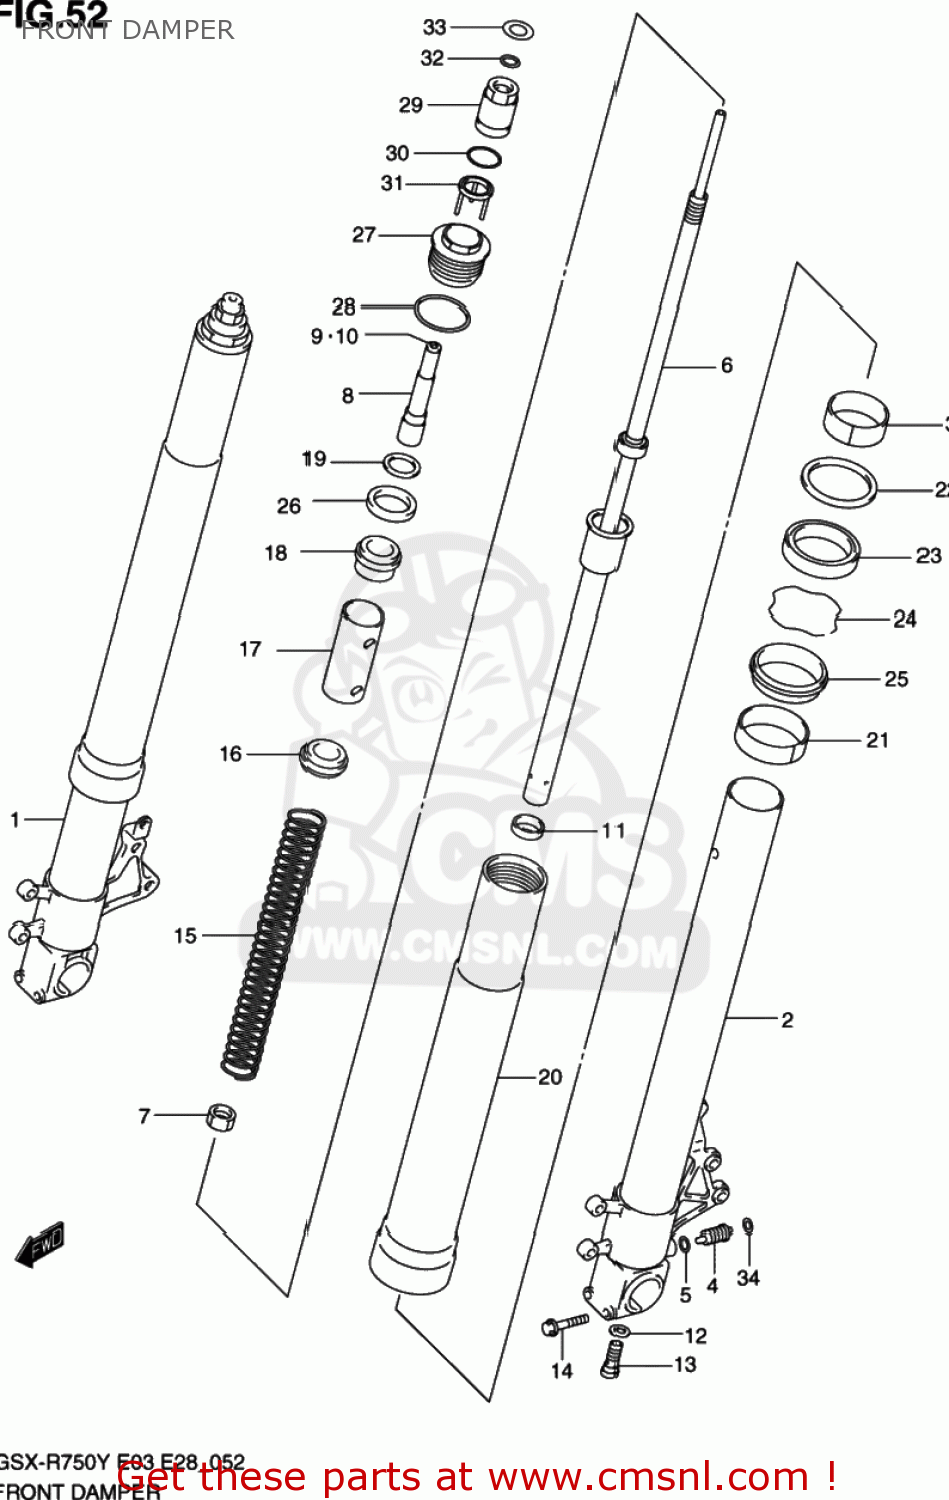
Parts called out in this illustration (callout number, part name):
1	TUBE,INNER,R
2	TUBE,INNER,L
3	BUSH,SLIDE
4	PIECE,ADJUST
5	O RING(D:2.5,ID:13.8)
6	ROD,FR DAMPER
7	NUT
8	CASE,ADJUSTER
9	PIECE,ADJUST
10	O RING(D:1.9,ID:3.8)
11	PLATE,CENTERING
12	WASHER(10X15X1.5)
13	BOLT
14	BOLT
15	SPRING,MAIN
16	JOINT,SPRING
17	COLLAR,SPRING
18	GUIDE,SPRING UPR
19	GUIDE,SPRING
20	TUBE,OUTER
21	BUSH,GUIDE
22	SPACER,SEAL
23	SEAL,OIL
24	CIRCLIP,FORK OIL SEAL
25	SEAL,DUST
26	RUBBER,SEAT
27	BOLT,FORK
28	O RING,FORK BOLT
29	ADJUSTER,SPRING
30	O RING
31	PLATE,SPRING ADJUSTER
32	RING,STOPPER
33	LABEL,ADJUST PIECE UPR
34	LABEL,ADJUST PIECE LWR
